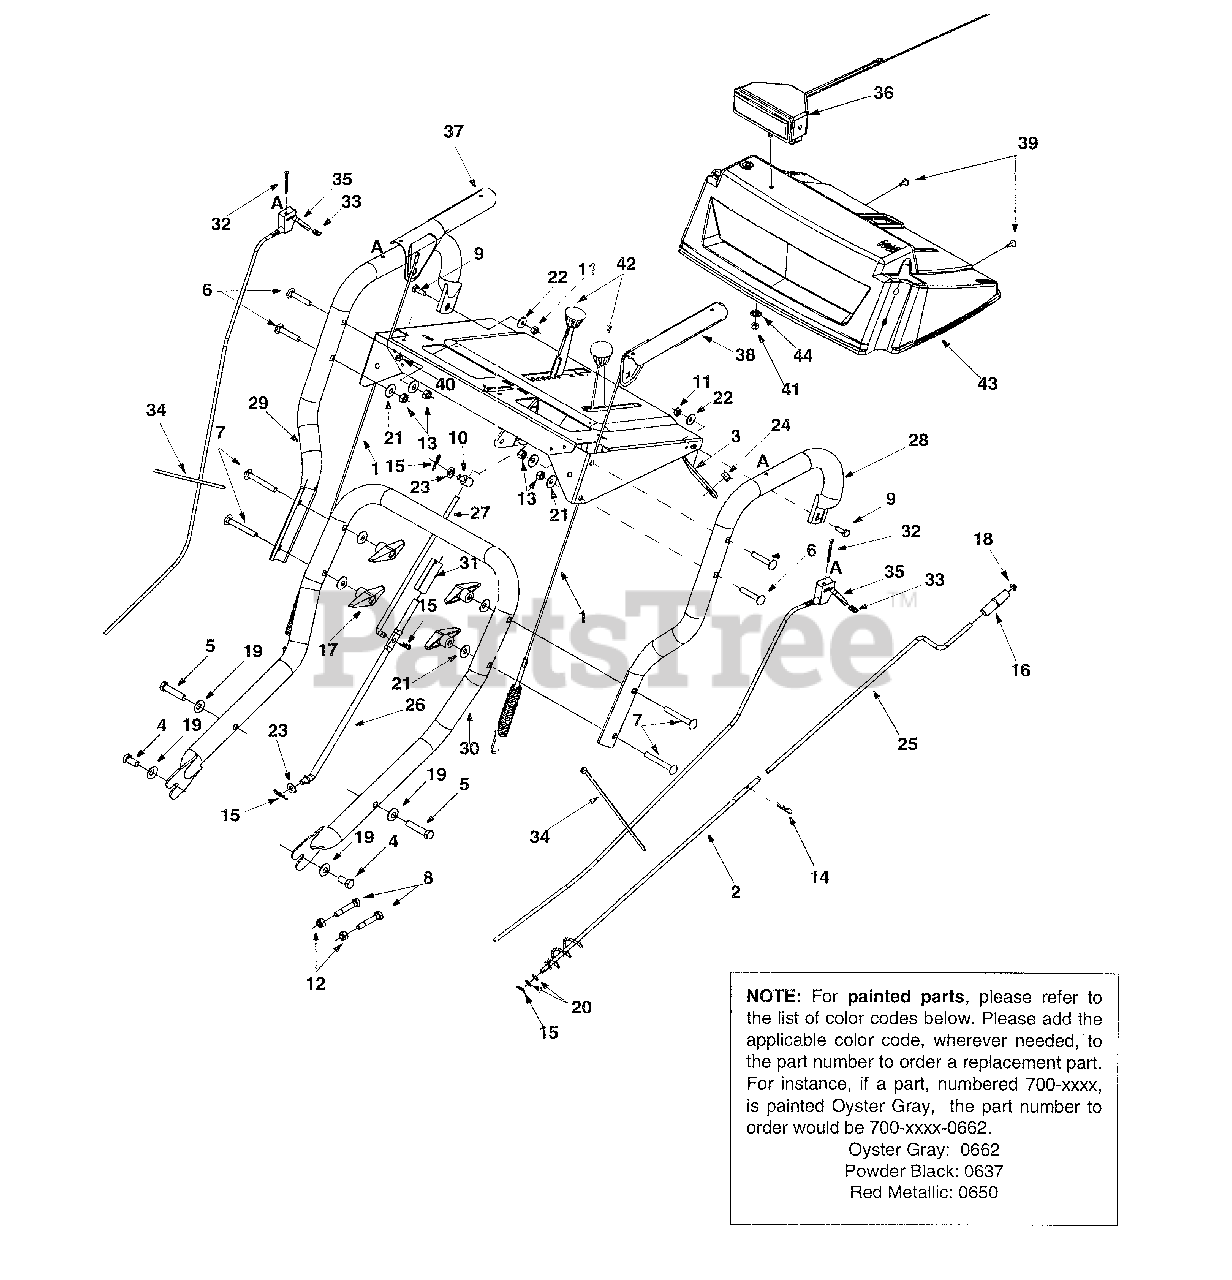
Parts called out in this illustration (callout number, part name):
1	Cable Assembly: Auger/Drive Engagement
4	Hex Screw 3/8-16 x .75"
5	Hex Screw 3/8-16 x 1.75"
6	Carriage Bolt 5/16-18 x 1.75"
7	Carriage Bolt 5/16-18 x 2.5"
8	Shear Bolt 5/16-18 x 1.75"
9	Hex Screw 1/4-20 x .75"
10	Ferrule
11	Hex Nut 1/4-20
12	Hex Lock Nut
14	Hairpin Clip
15	Hairpin Clip
16	Chute Crank Knob
21	Beleville Washer
24	Plastic Bushing
26	Lower Shift Rod
27	Upper Shift Rod
31	Clutch Rod Connector
32	Oval C-Sunk Screw
33	Flat Weld Nut
35	Trigger Control
36	Light Assembly
37	Handle Engagement RH
38	Handle Engagement LH
39	Special B Screw
40	Hex Sems Nut
41	Hex Lock Nut
42	Shift Knob
43	Handle Panel
